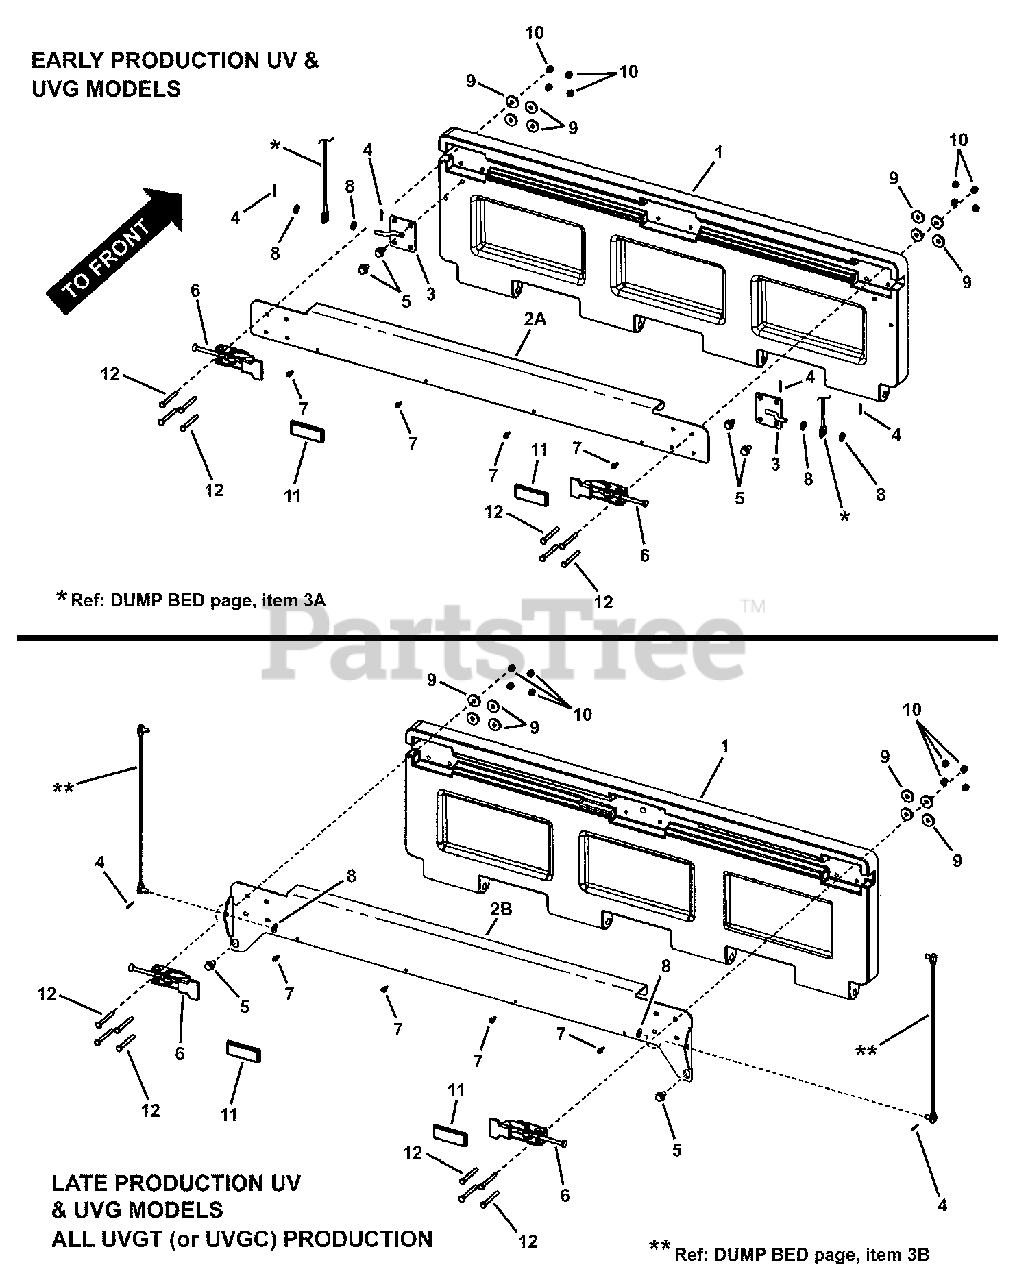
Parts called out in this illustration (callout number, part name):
1	TAILGATE, Plastic
2A	* COVER, Tailgate
2B	COVER, Tailgate
3	* BRACKET, Gate (weldment)
4	COTTER PIN, 3/32 x 3/4"
5	BOLT, 5/16-18 x 5/8" Hex Flange Lock
6	LATCH, Tailgate
7	SCREW, #10 x 5/8" HiLo Nail Point
8	WASHER, .34 x .69 x .08 Flat
9	WASHER, .281 x 1.00 x .125 Flat
10	NUT, 1/4-20 Hex Nyloc
11	REFLECTOR, Red
12	SCREW, 1/4-20 x 2-1/4" Hex Head Cap, GR 5
